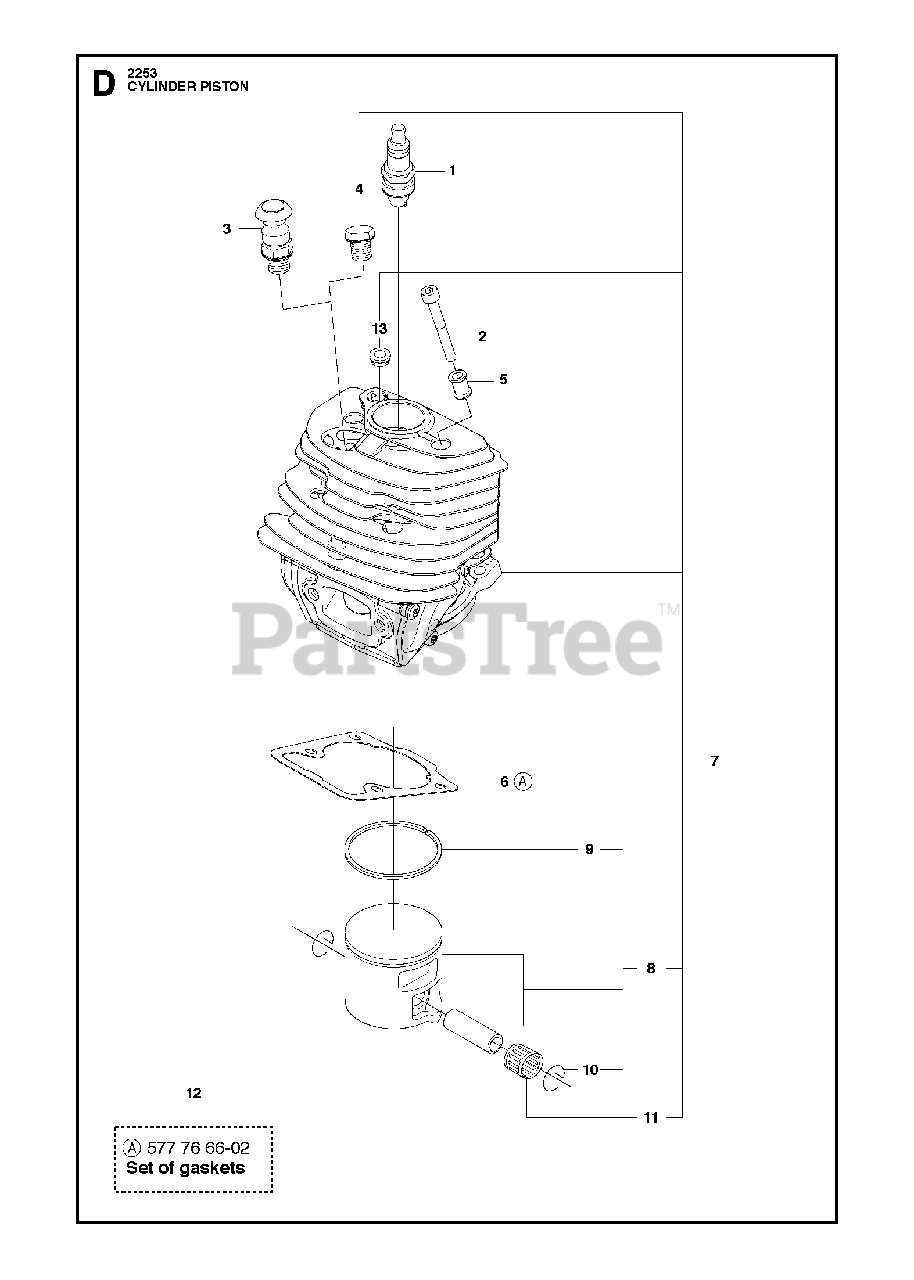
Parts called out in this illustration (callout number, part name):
1	CMR6H SPARK PLUG NGK
2	SCREW MC6S 5X40
3	DECOMPRESSION VALVE
4	CYLINDER PLUG
6	GASKET
7	CYLINDER-PISTON ASSY
8	PISTON ASSY
10	LOCKING RING
11	NEEDLE BEARING
13	BUSHING
